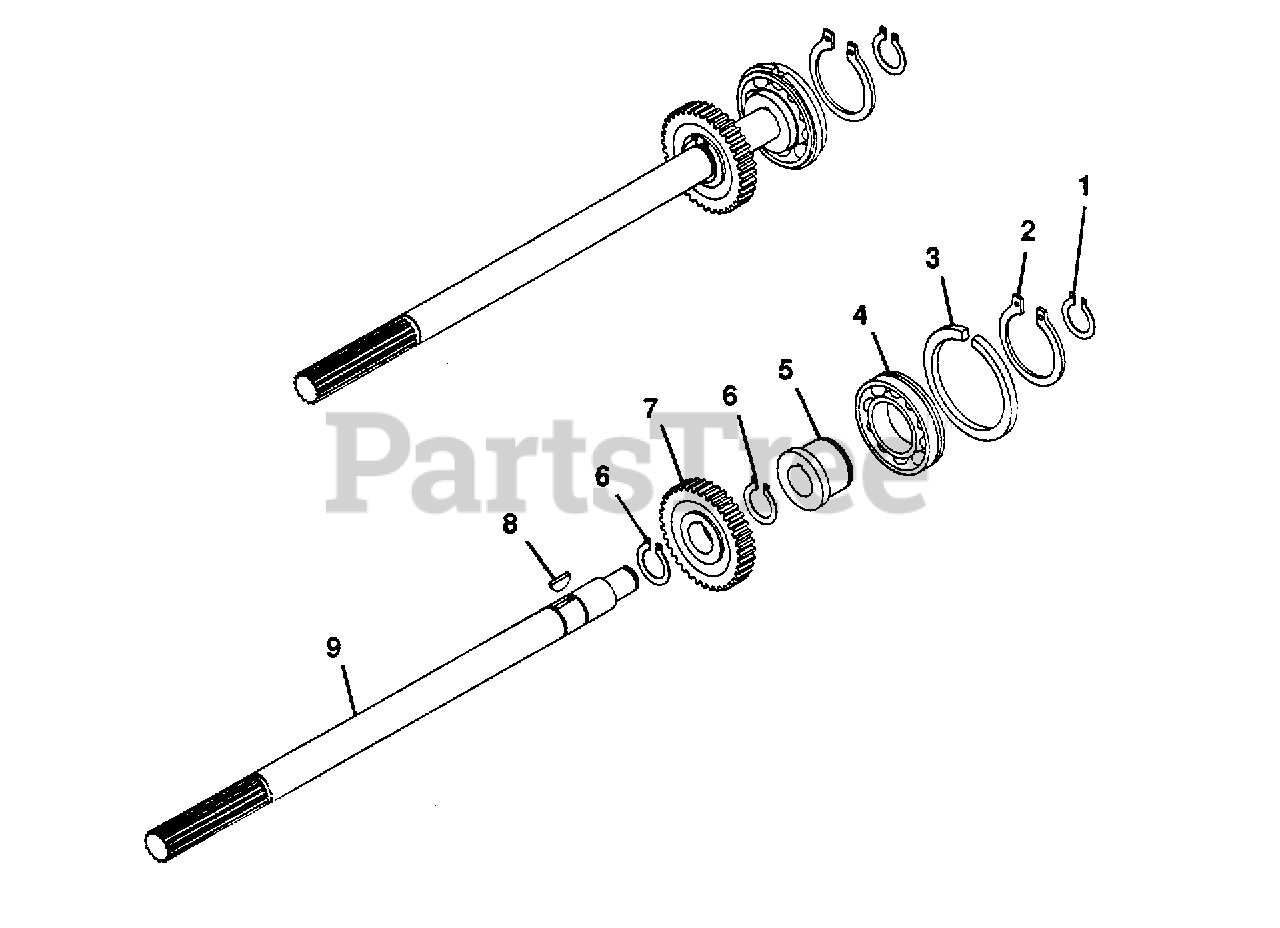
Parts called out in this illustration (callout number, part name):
1	RING, RETAINING .750 SHAFT
2	RING, RETAINING
3	RING, RETAINING
4	BEARING, BALL 1.378X2.440X.551
5	ADAPTER, PTO BEARING
6	RING, RETAINING .984 SHAFT
7	GEAR, PTO CROSS SHAFT
8	KEY, WOODRUFF .187X.750 HRD #9
9	SHAFT, PTO
